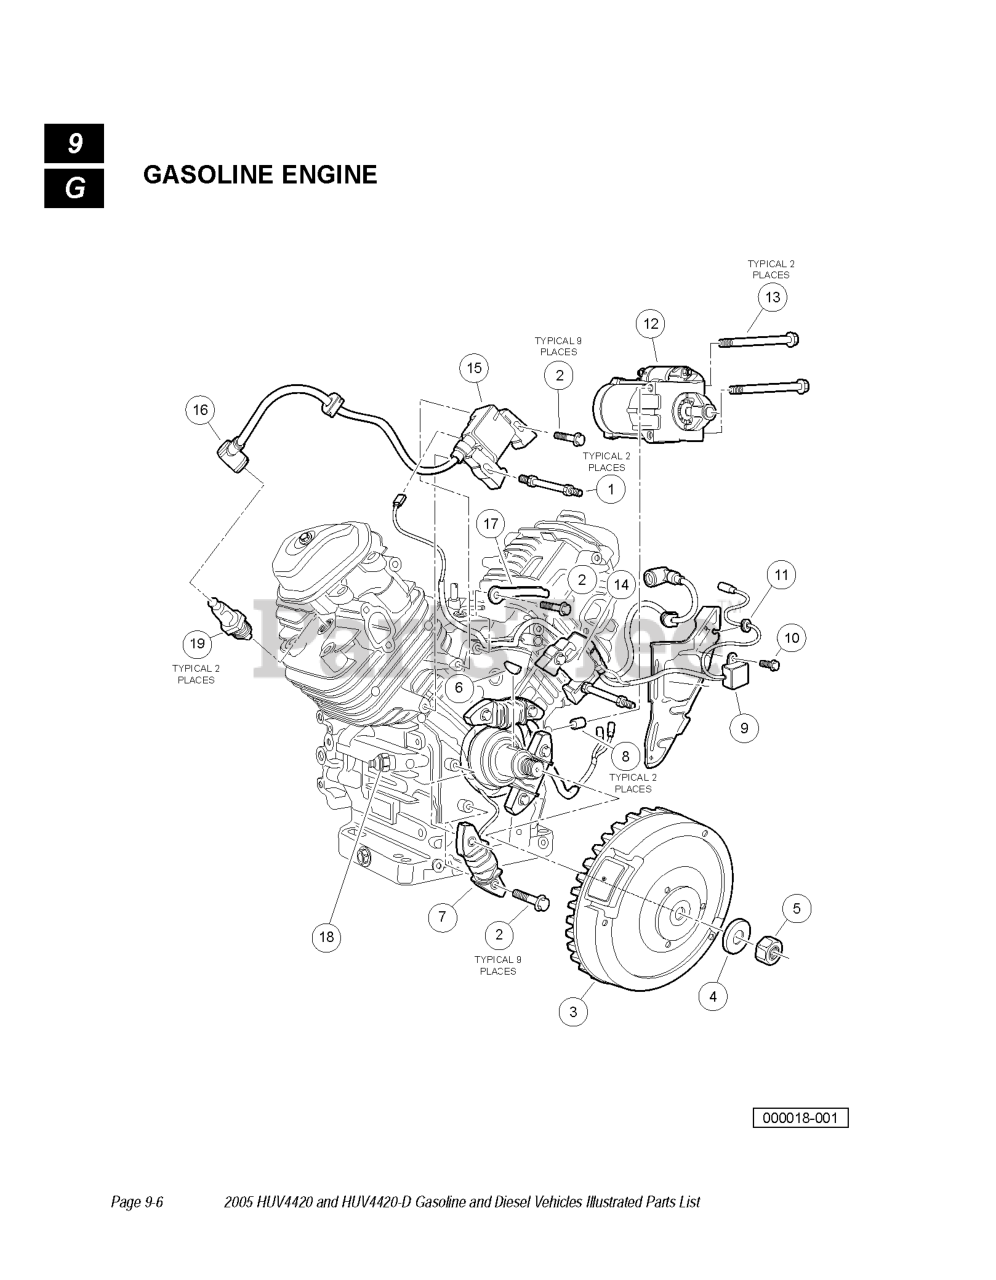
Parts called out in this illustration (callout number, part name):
1	STUD, ENGINE
2	BOLT, FLANGE, M6 X 1 X 32
4	WASHER, M20
5	WASHER, M20
6	KEY, SPECIAL WOODRUFF, 25 X 18
7	COIL ASSY, CHARGE, 12V/20A
8	PIN, DOWEL, 10 X 12
9	DIODE ASSY, ENGINE STOP
10	BOLT, FLANGE, M6 X 1 X 8
11	GROMMET, TOOL
12	MOTOR ASSY, STARTER
13	BOLT, FLANGE, M8 X 1.25 X 110
14	COIL ASSY, R, IGNITION
15	COIL ASSY, L, IGNITION
16	CAP ASSY, NOISE SUPPRESSOR
17	CLAMP, WIRE
18	SWITCH, PRESS, OIL, GX620
19	Spark Plug, BPR2ES
